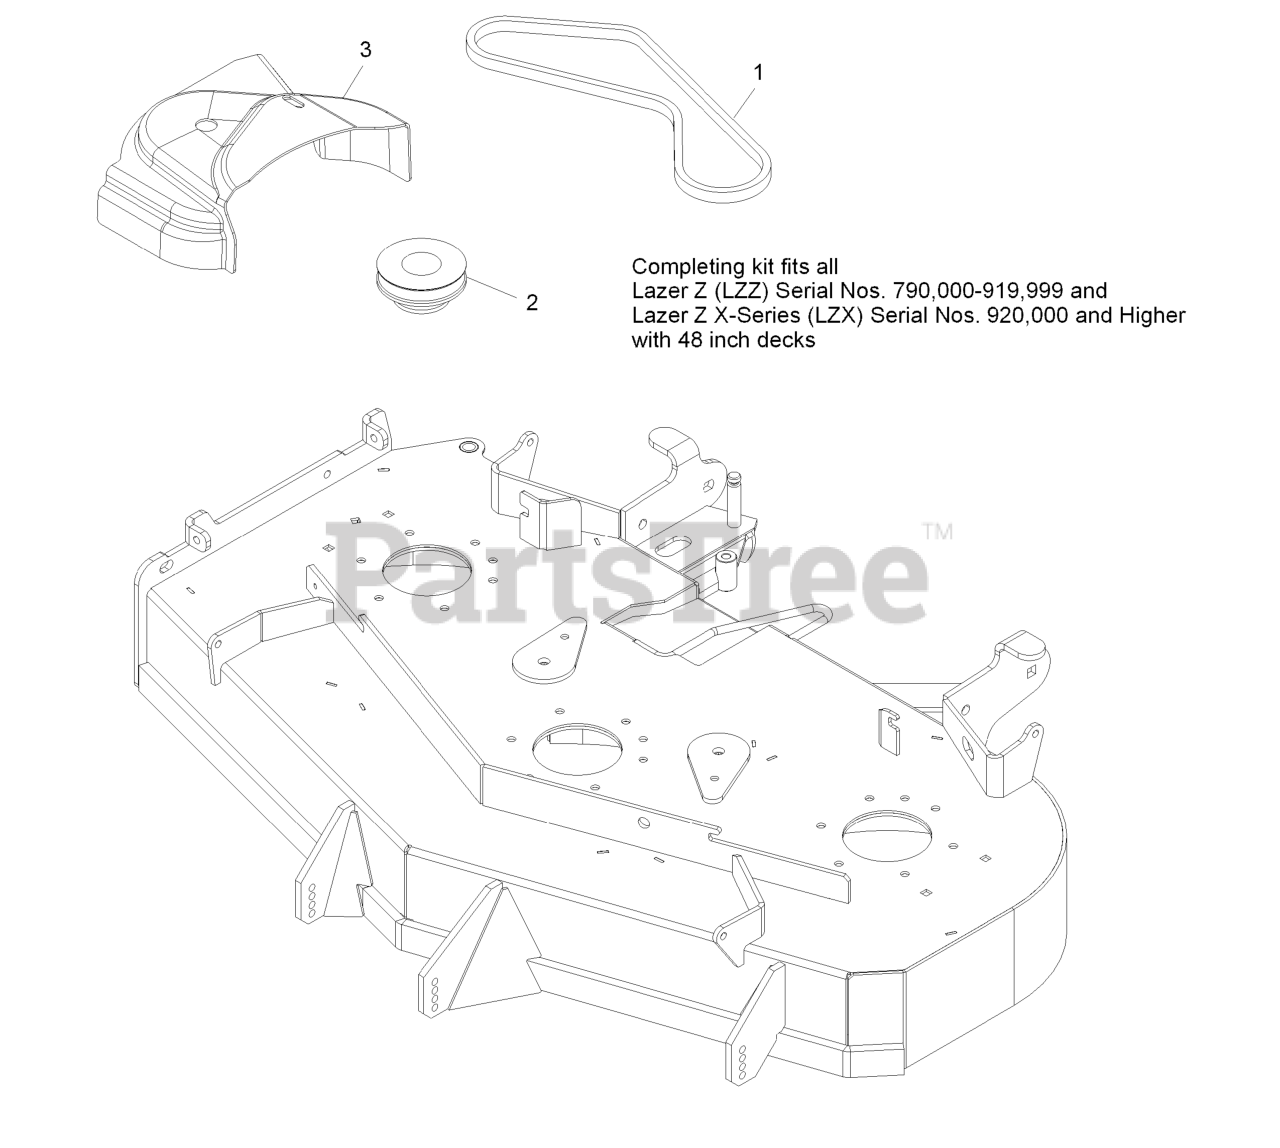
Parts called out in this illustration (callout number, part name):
1	BELT-BLOWER
2	SHEAVE,DRIVE LZUV 486
3	COVER,BELT UV 48
